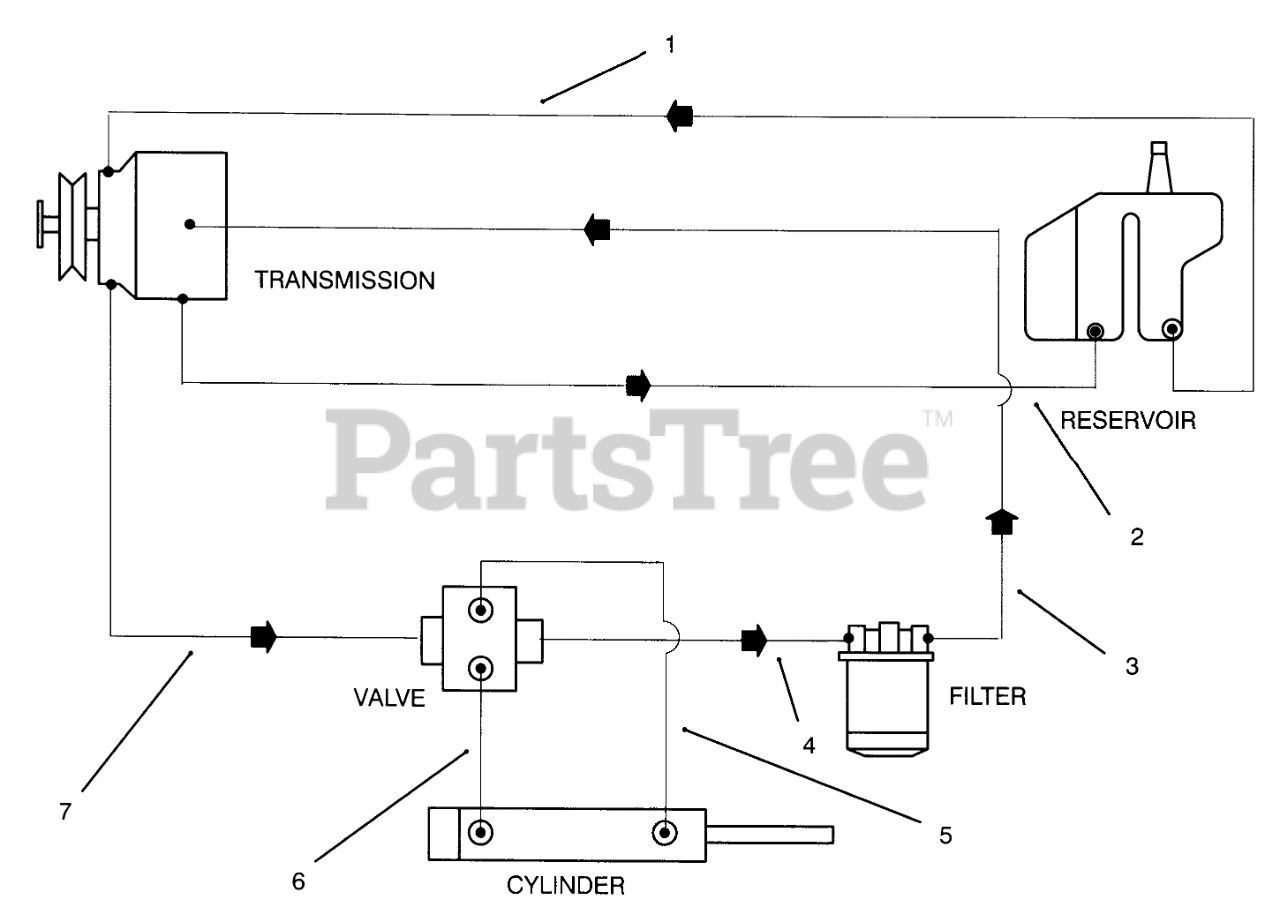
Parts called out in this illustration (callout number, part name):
1	HOSE ASM
2	TUBE ASM
3	HOSE ASM
4	Hydraulic Hose Assembly Valve to Filter
5	HOSE ASM
6	HOSE ASM
7	HOSE ASM
